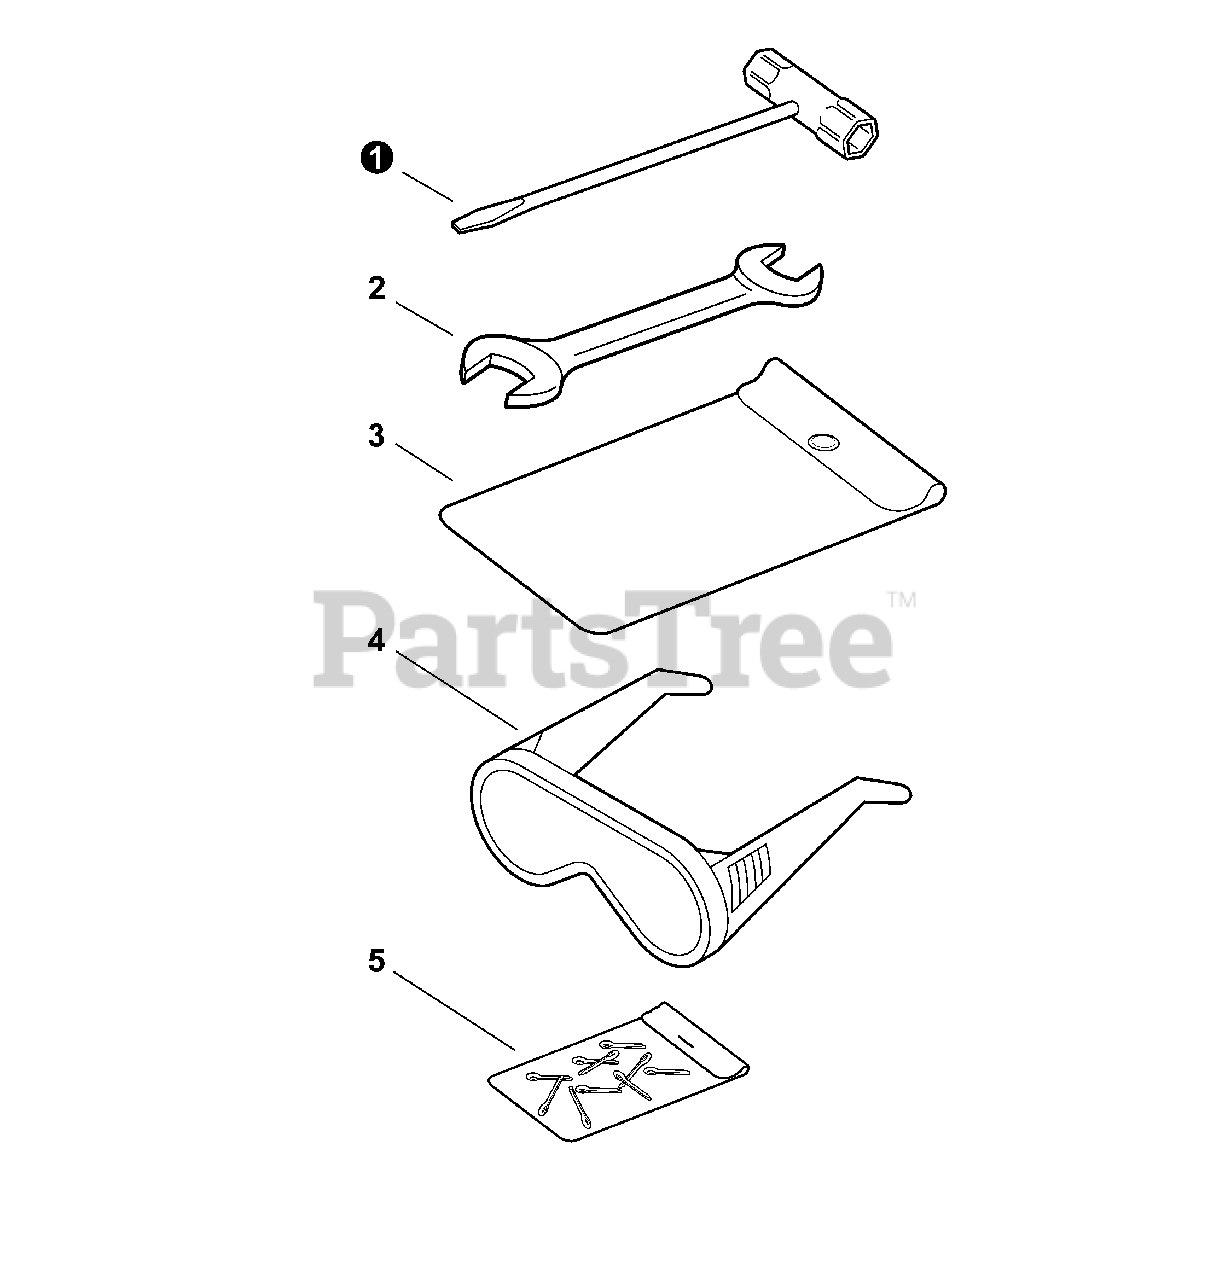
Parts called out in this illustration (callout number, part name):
1	T-WRENCH 17x-19 L200
2	NAMEPLATE
3	BAG, TOOL
4	GLASSES, SAFETY
5	PIN, COTTER 2×22
